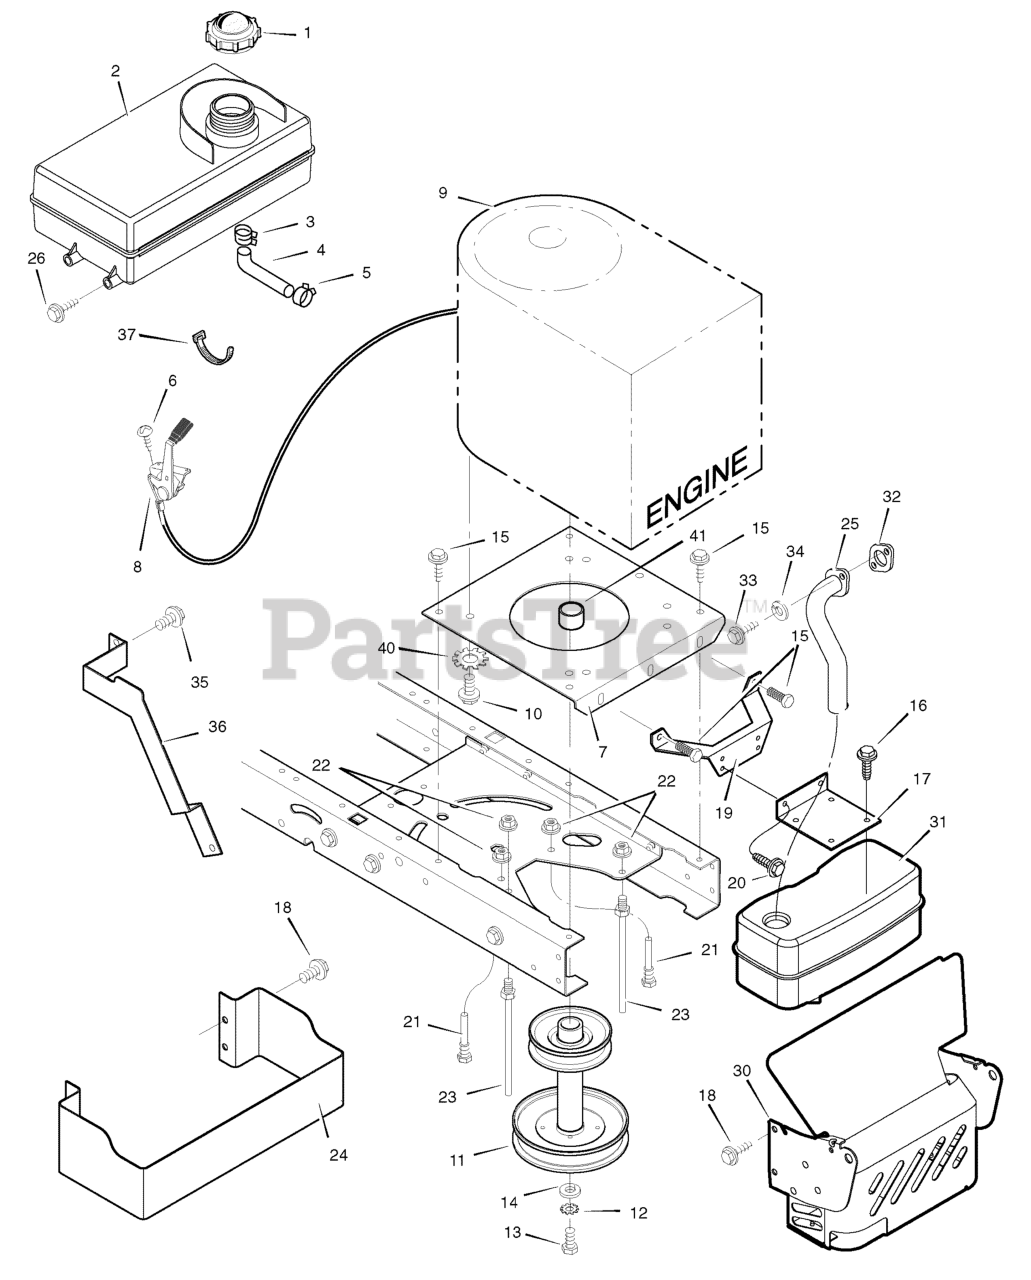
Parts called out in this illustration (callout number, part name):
1	Fuel Cap **
2	TANK, Fuel 1.4 Gal.
3	Hose Clamp
4	Fuel Line (Must cut to length)
5	Hose Clamp
7	Plate, Engine
8	Throttle Control
9	Engine, Briggs & Stratton *
10	Bolt, Engine Mount
11	STACK PULLEY ASSEMBLY
12	Lockwasher
13	Bolt, Hex
17	Bracket, Muffler
19	Bracket, Muffler Mount
21	Guide, Belt
22	Nut, Flange
23	Guide, Screw
24	GUARD, Heat Shield
25	Exhaust Tube, Single
30	Shield, Heat
31	Muffler
32	GASKET, Exhaust
34	Washer
35	Bolt, Washer Hex Head
36	Guard, Exhaust Pipe
37	Tie, Strap Black
40	Washer 3/8 x .03 Star
41	Spacer, Engine
